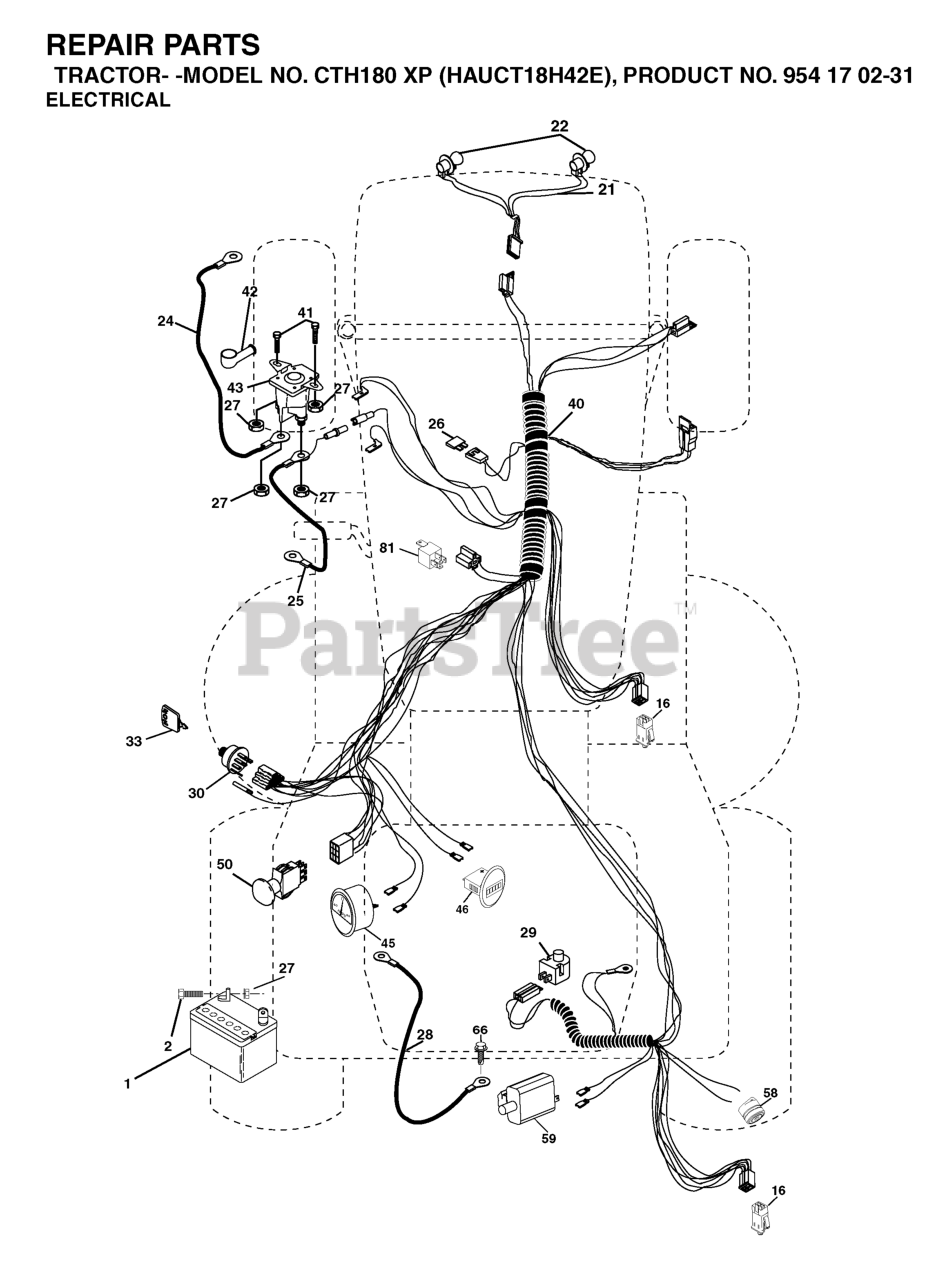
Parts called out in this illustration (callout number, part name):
1	BATTERY 12V .35 AMP
2	BOLT.HEX.1/4.X.3/4.DICHROMATE
16	SWITCH INTERLOOK PUSH-IN
21	HARNESS.W/LIGHT SOCKET
24	BATTERY CABLE GT
25	CABLE BATTERY
26	FUSE 20AMP
27	NUT
28	CABLE GROUND
29	RP.SWITCH.PLUNGER.NC.GRAY
30	IGNITION SWITCH
33	KEY MLD GEN DELTA
41	BOLT
42	TERMINAL COVER
43	SOLENOID
45	RP AMMETER.ROUND.SILVER.DELTA
46	RP HOURMETER SNAP-IN
50	RP.PTO.SWITCH.8 TERMINAL.BLACK
58	BUZZER
59	.WITCH.FULL BAGGER.INDICATOR
79	BULB HOLDER ASM.
81	RELAY.ASSY.T
